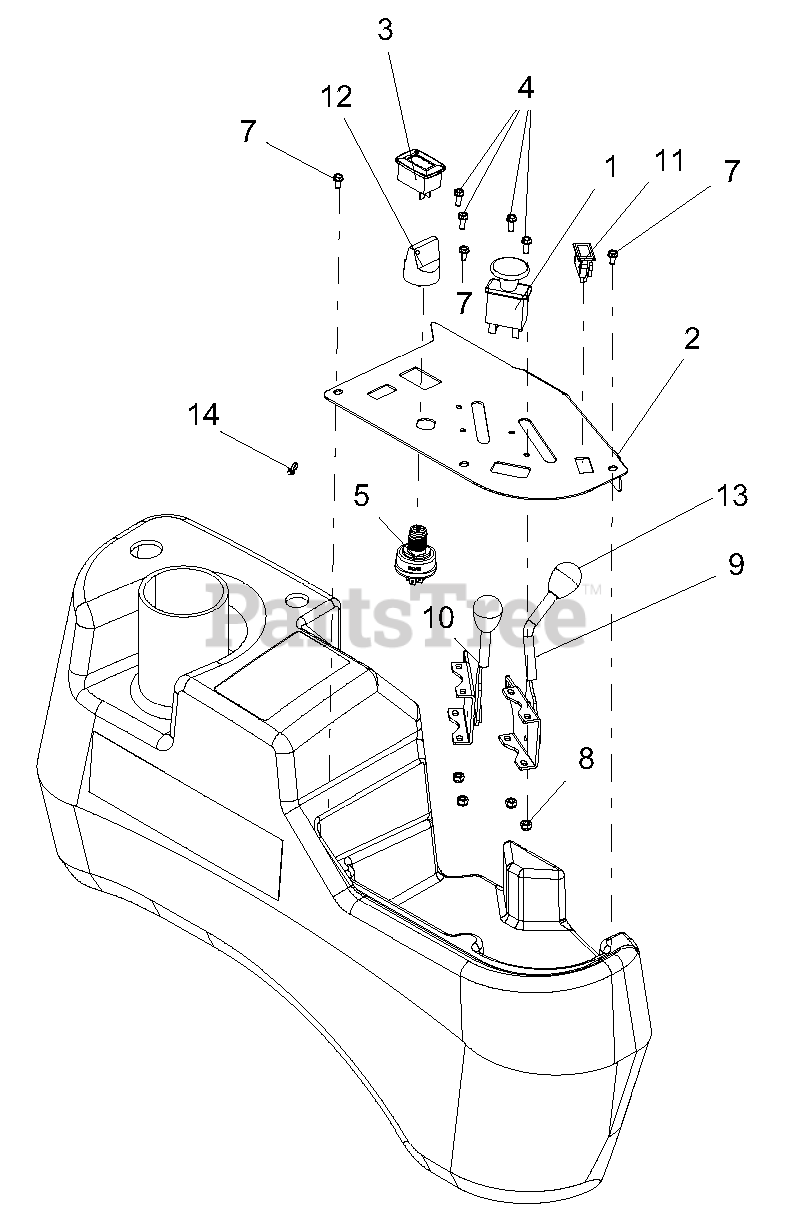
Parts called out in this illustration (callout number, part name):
1	SWITCH, CLUTCH
2	PANEL, CONTROL
3	METER, HOUR W/MAINTENANCE
4	SCR-MCH 10-24X.50 HWH YWZC
5	SWITCH, IGNITION
7	SCR, HWH 10-24x.38 STAINLESS
8	NUT-LK-NYL #10-24 YWZC
9	CABLE, PRO-CONTROL THROTTLE
9	CABLE-THROTTLE 53"
10	CABLE, PRO-CONTROL CHOKE
11	LIGHT, INDICATOR
12	KEY, W/ COVER
13	KNOB, CONTROL BLACK .38-16X.50
14	CABLE TIE W/ TREE
